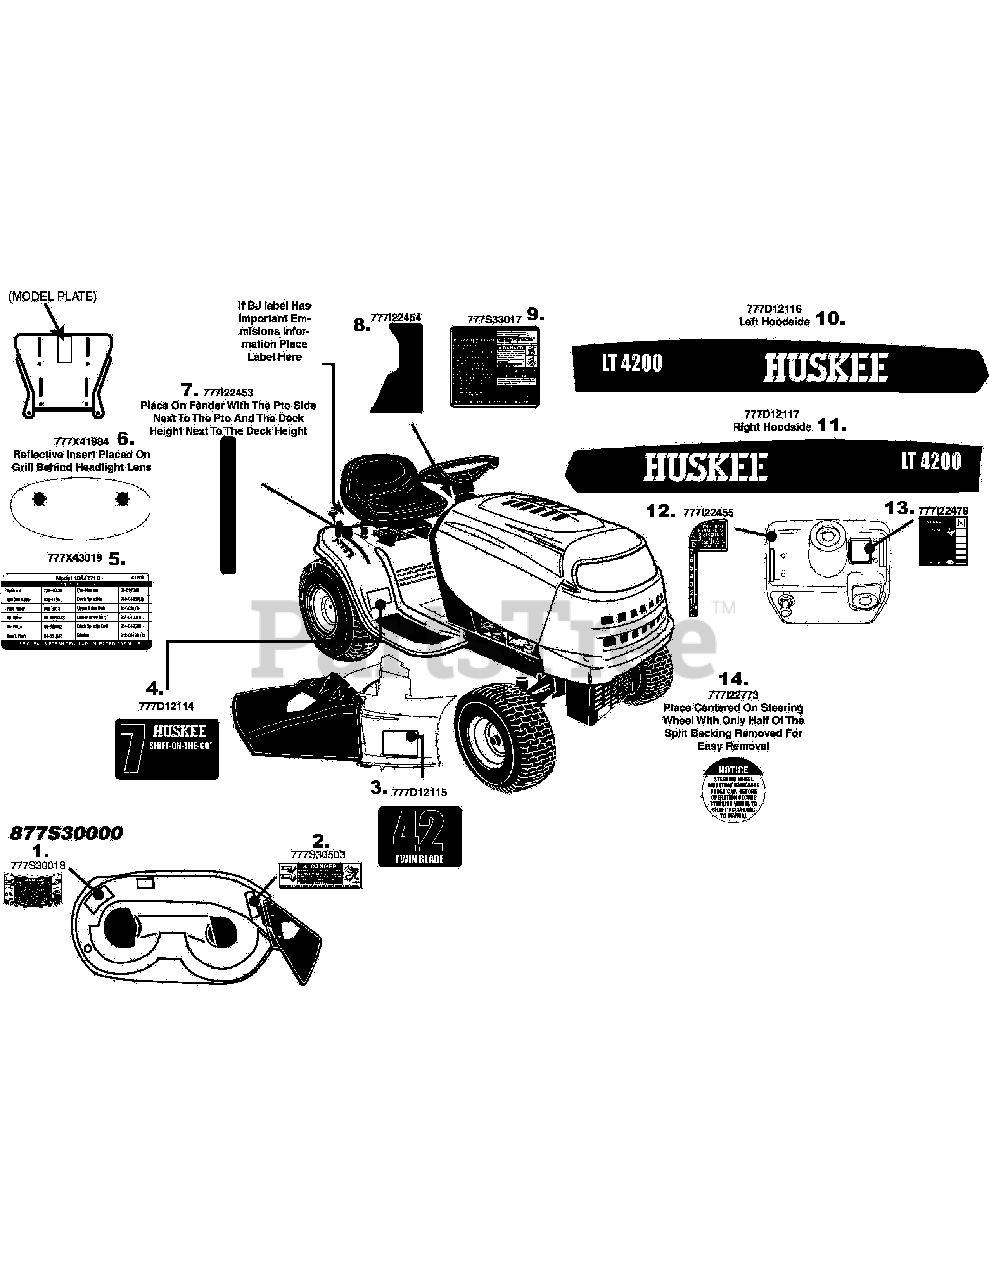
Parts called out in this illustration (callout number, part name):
1	LABEL-DECK SAFETY
2	LABEL-DANGER CHUTE
3	LABEL-RIDER DECK HUSKEE 42 TWIN
4	LABEL-RIDER FENDER HUSKEE 7SP
5	LABEL-RIDER PARTS LIST
6	LABEL:RIDER 1&5 STYLE GRILL
7	LABEL:RIDER LT-5 FENDER
8	LABEL:RIDER LT-5 FENDER
9	LABEL-LT 5 TRANS COVER NO OCR
10	LABEL-RIDER HOOD LH LT4200 HUSKEE
11	LABEL-RIDER HOOD RH LT4200 HUSKEE
12	LABEL:RIDER LT-5 DASH
13	LABEL: RIDER LT-5 THRT/CHK
14	LABEL-RIDER:SECURE WHEEL
